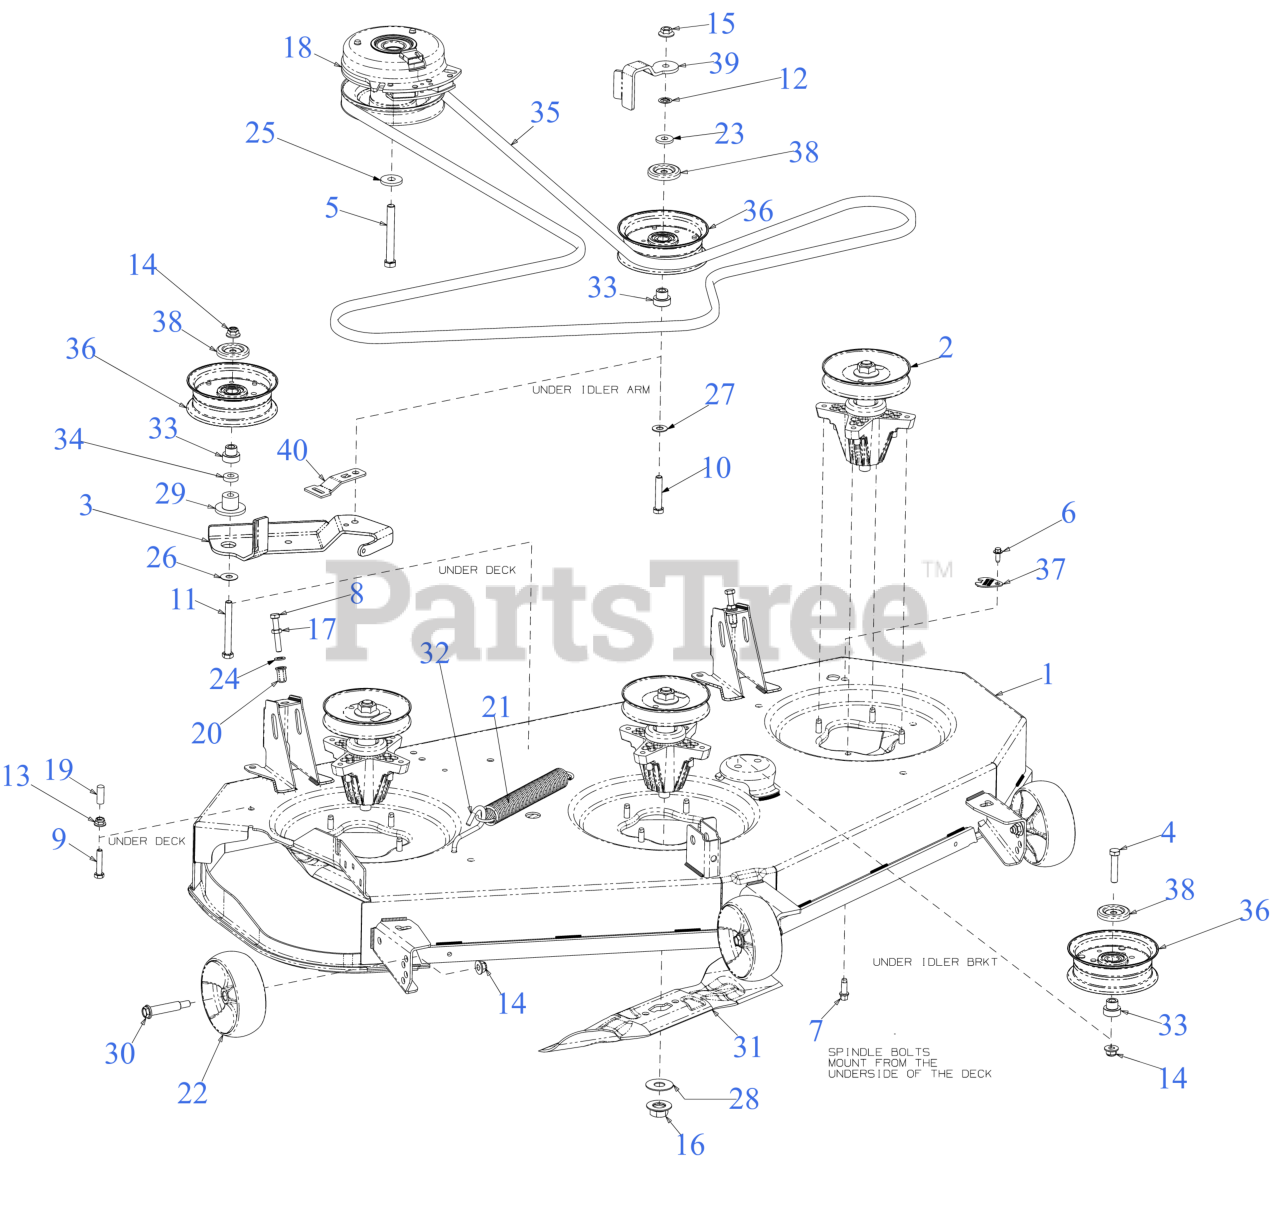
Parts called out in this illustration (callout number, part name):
1	50" FAB DECK SHELL
2	SPINDLE ASSEMBLY (5.37 DIA)
3	DECK IDLER BRACKET
4	HEX SCREW 3/8-16 x 1.75 GR5
5	SCREW 7/16-20 x 3.5 GR5
6	SCREW M6-1 x .625
7	SCREW 5/16-18 x .875
8	SCREW-FULL THREAD 5/16-18 GR5
9	SCREW 5/16-18 x 1.5 LG
10	SCREW 3/8-16 x 2.0 GR 8
11	SCREW 3/8-16 x 3.25 GR8
13	FLANGE LOCK NUT 5/16-18
15	FLANGE LOCK NUT
16	HEX FLANGE NUT 5/8-18 GR5
18	ELECTRIC PTO CLUTCH
20	NUT RIVET 5/16-18
21	EXTENSION SPRING
22	DECK WHEEL (5.0 DIA x 1.875)
23	FLAT WASHER .385 x 1.00 x .135
24	FLAT WASHER
25	FLAT WASHER .445 x 1.248 x .170
26	FLAT WASHER
27	FLAT WASHER .401X.88
28	FLAT WASHER .635X1.585X.062 HDN
29	SHOULDER SPACER
30	SHOULDER BOLT (.50 X 2.0 x 3/8 -16)
31	17.271" BLADE (2IN1) (S SHAPE CENTER HOLE)
31	Cub Cadet 50" HI LIFT BLADE SET (S SHAPE CENTER HOLE) (-05094)
31	Troy-Bilt 50" HI LIFT BLADE SET (S SHAPE CENTER HOLE)
31	17.271" XTREME BLADE (2IN1) (S SHAPE CENTER HOLE)
31	Cub Cadet 50" XTREME BLADE SET (S SHAPE CENTER HOLE) (-05094-X)
31	Troy-Bilt 50" XTREME BLADE SET (S SHAPE CENTER HOLE)
31	17.271" LOW LIFT (S SHAPE CENTER HOLE)
31	Cub Cadet 50" LOW LIFT BLADE SET (S SHAPE CENTER HOLE) (-05094-X)
31	Troy-Bilt 50" LOW LIFT BLADE SET (S SHAPE CENTER HOLE)
32	DECK SPRING HOOK
33	SHOULDER SPACER
35	V-BELT B SEC x 143.5 LG
35	Cub Cadet 50" DECK DRIVE BELT
35	Genuine Factory Parts 50" DECK BELT
36	IDLER PULLEY 4.50" DIA
37	DECK WASH PLUG
38	IDLER PULLEY CAP
39	BELT KEEPER
